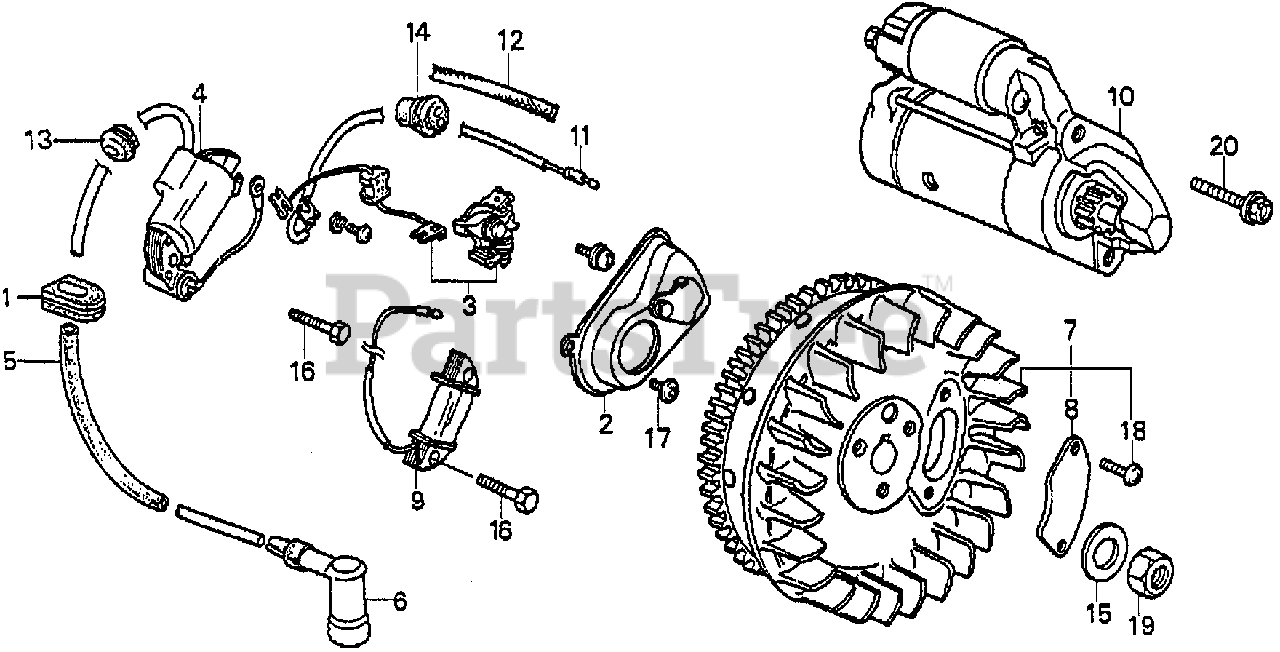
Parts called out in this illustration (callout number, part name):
1	GROMMET, WIRE
2	COVER, POINT
3	POINTS ASSY.
4	COIL, IGNITION (KOKUSAN)
5	TUBE, IGNITION RUBBER (NOT AVAILABLE)
6	CAP ASSY., NOISE SUPPRESSOR
7	MAGNETO, FLYWHEEL
8	COVER, FLYWHEEL WINDOW (NOT AVAILABLE)
9	COIL, CHARGING (NOT AVAILABLE)
10	MOTOR ASSY., STARTER (NOT AVAILABLE)
11	WIRE, ENGINE STOP
12	TUBE, HEAT RESIST
13	GROMMET, WIRE
14	GROMMET, WIRE
15	WASHER (14MM) (NOT AVAILABLE)
16	BOLT, HEX. (6X28)
17	SCREW, PAN (5X6)
18	SCREW, PAN (5X8)
19	NUT, HEX. (14MM)
20	BOLT, FLANGE (8X32)
